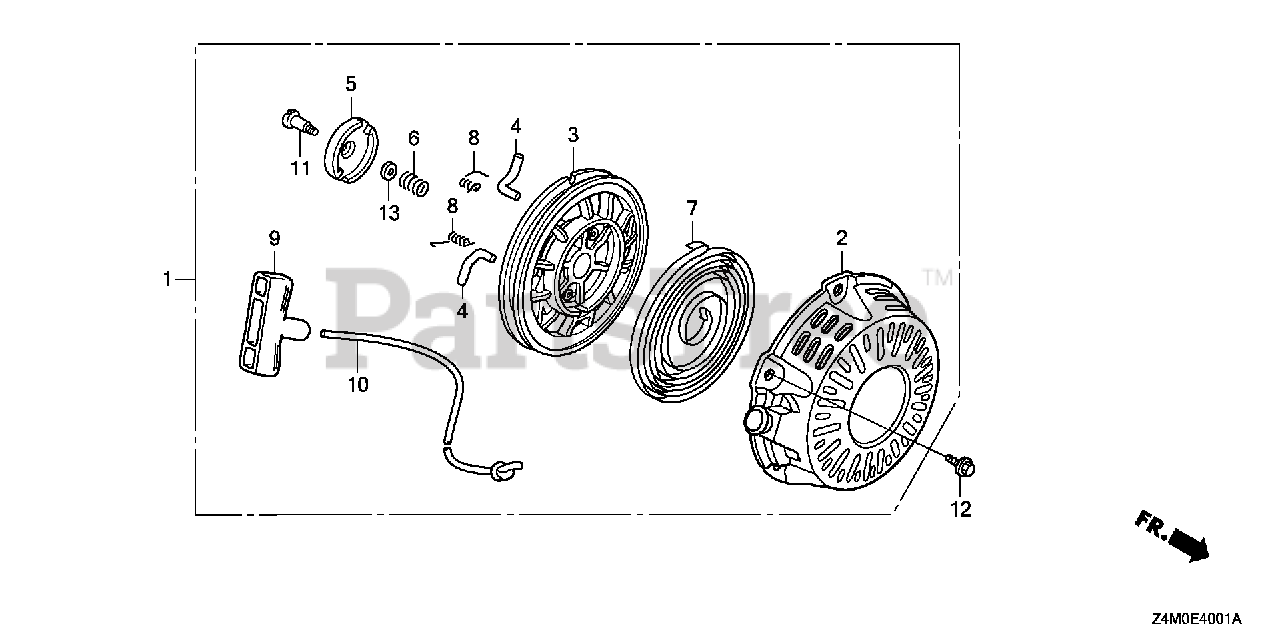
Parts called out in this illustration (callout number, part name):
1	STARTER ASSY., RECOIL *NH1* (BLACK)
2	CASE, RECOIL STARTER *NH1* (BLACK)
3	REEL, RECOIL STARTER
4	RATCHET, STARTER
5	GUIDE, RATCHET
6	SPRING, FRICTION
7	SPRING, RECOIL STARTER
8	SPRING, RETURN
9	KNOB, RECOIL STARTER
10	ROPE, RECOIL STARTER
11	SCREW, SETTING
12	BOLT, FLANGE (6X10)
13	PLATE, FRICTION
